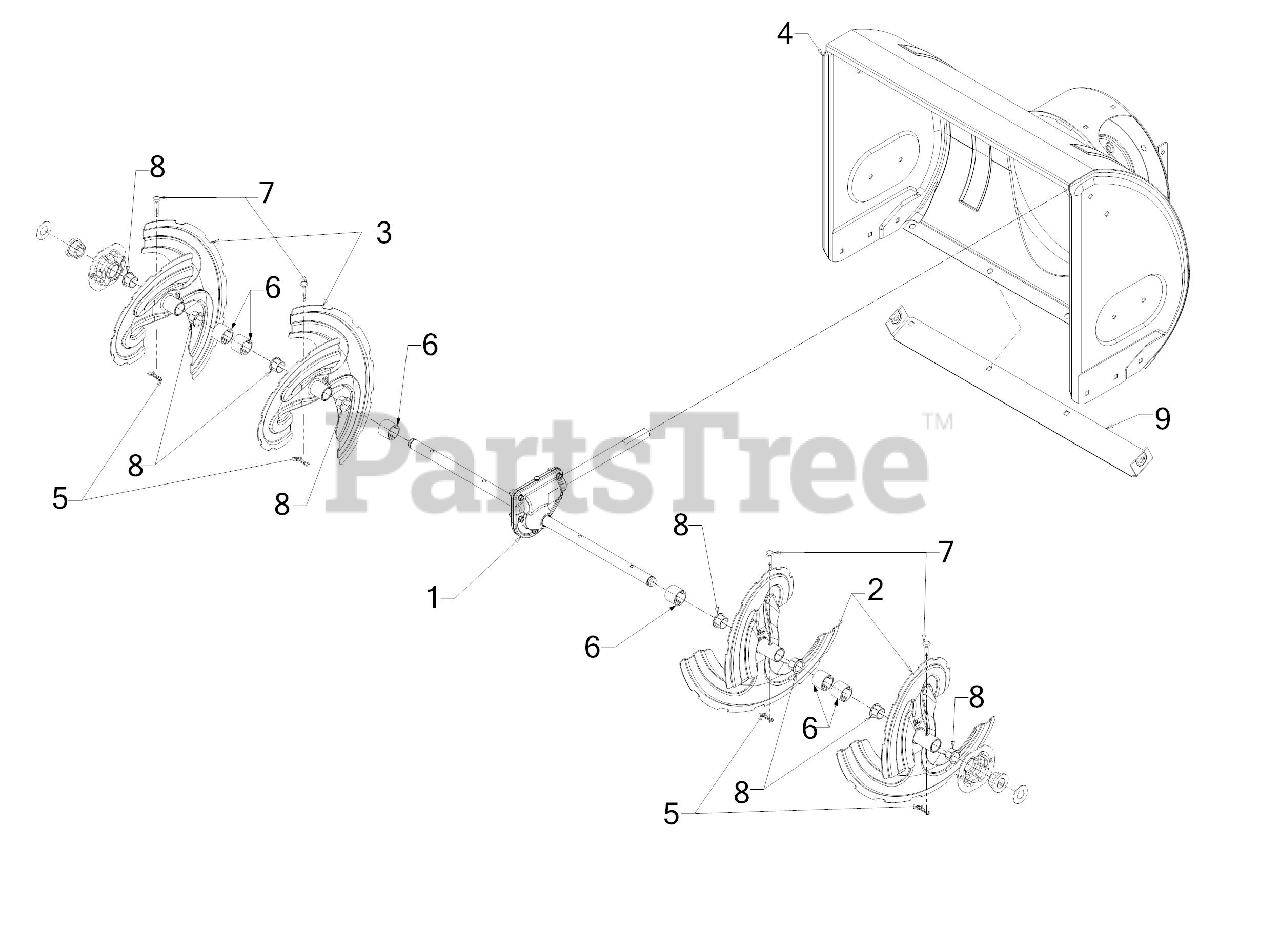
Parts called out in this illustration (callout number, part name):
1	26" GEARBOX ASSEMBLY
5	BOW TIE COTTER PIN 1/4-5/16
6	SPACER 1.25OD x .75ID X1.00 LG
7	SHEAR PIN .25 x 1.50 GR2
8	FLANGE BUSHING
